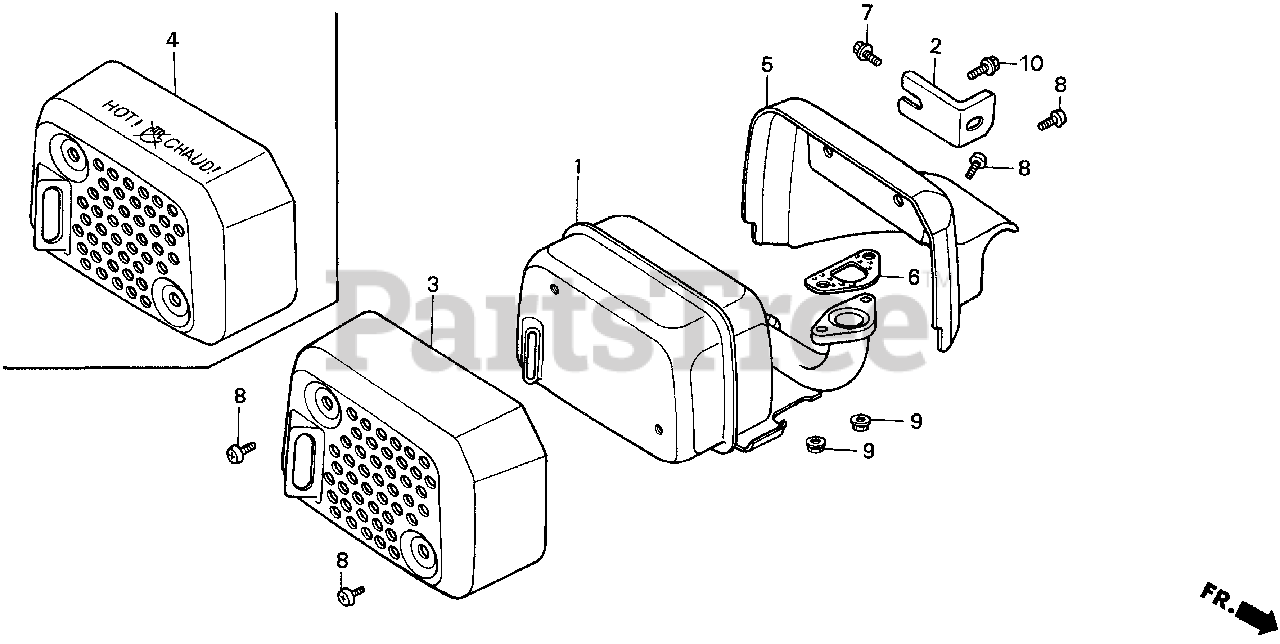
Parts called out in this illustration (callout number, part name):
1	MUFFLER COMP.
2	STAY, MUFFLER
3	PROTECTOR, MUFFLER
5	COVER, EX. (UPPER)
6	GASKET, MUFFLER Use from Engine SN 2506046.
7	BOLT, FLANGE (6X14)
8	SCREW, PAN (6X6)
9	NUT, FLANGE (6MM)
10	BOLT, FLANGE (6X12) Use up to Engine SN 1543277.
